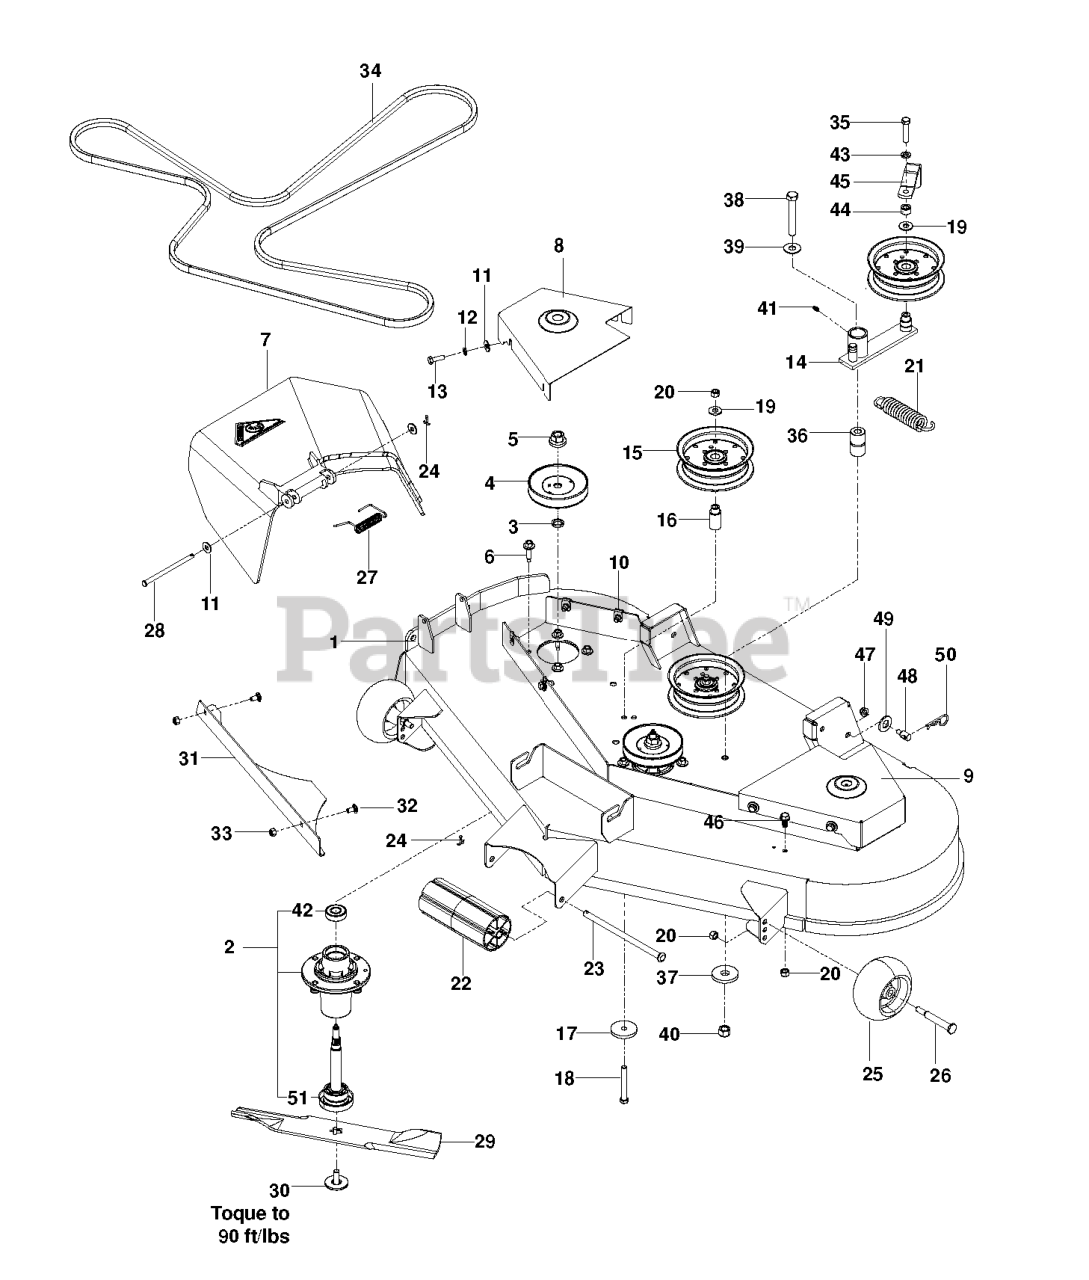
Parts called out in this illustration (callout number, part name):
1	DECK.48".TRI-FORCE.W/DECALS.OR
2	MANDREL.DECK.ASSEMBLY
3	WASHER-SPACER
4	MANDREL PULLEY
5	LOCKNUT - 9/16
6	WASHER HEAD SCREW
7	DISCHARGE CHUTE 48"
8	BELT SHIELD - R.H. ORANGE
9	BELT SHIELD - L.H. ORANGE
10	U-CLIP 5/16-18 NUT RETAINER
11	WASHER 5/16 FLAT
12	WASHER.LOCK.HVY.HLCL.SPR.5/16
13	HCS 5/16C X 1
15	PULLEY, IDLER
16	IDLER BUSHING
17	SPINDLE WASHER
18	HCS 3/8C X 3
19	WASHER 3/8 FLAT
20	NUT 3/8-16 NYLOC
22	NOSE ROLLER 48"
23	ROD.ROLLER.NOSE.NARROW.48"
24	RP_COTTER PIN 1/8 X 3/4
25	GAUGE WHEEL
26	SHOULDER BOLT 1/2X2-5/8 ZD SPE
27	SPRING - TORSION
28	PIN-CLEVIS 5/16 DIA X 5.19 ZD
29	BLADE, 16-1/4"
30	BLADE BOLT ASSY-7/16" TB REPL
31	CONFINEMENT PLATE 48" BLK
32	CARRIAGE BOLT 5/16C X 5/8"
33	NUT 5/16 NYLOC
34	BELT, DECK
35	HCS 3/8-16 X 1 3/4 GR5
36	PIVOT BUSHING
37	WASHER, SUPPORT
38	HCS 1/2C X 3 1/4
39	WASHER 1/2 FLAT
40	NUT 1/2-13 HEX NYLOC ZD
41	ZERK
42	BEARING, BALL
43	SLW 3/8 STD
45	GUIDE, BELT
46	SCREW, 3/8-16 X 3/4 THREAD CUT
47	5/16-18 NYLOC FLANGE NUT
48	STUD.FASTNER.W/ANTI-ROTATE
49	WASHER 5/8 FLAT
50	HAIRPIN #4
51	GREASABLE MANDREL SHAFT
